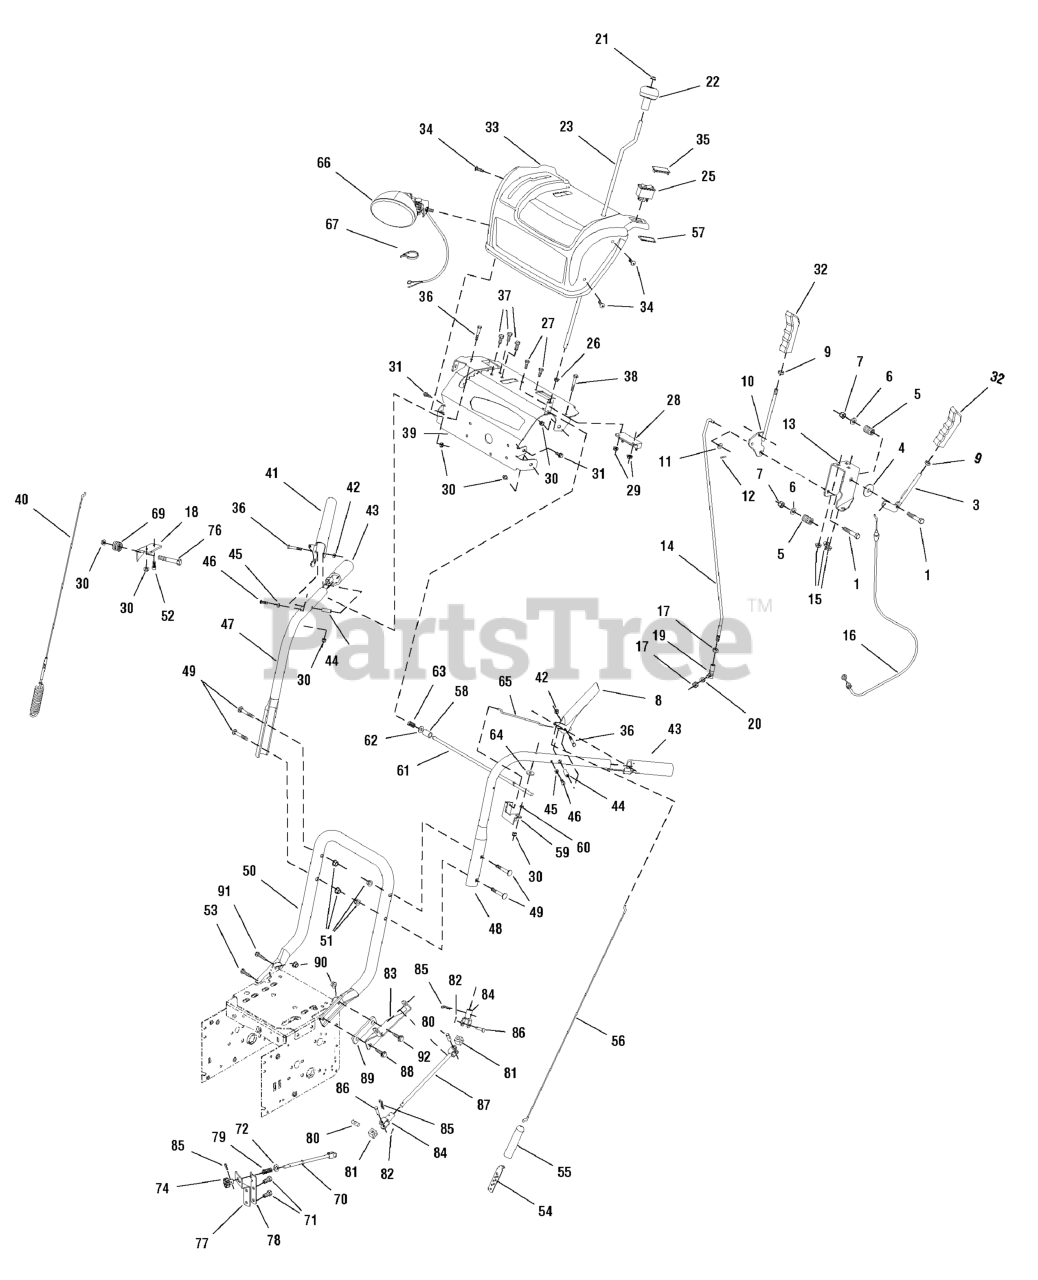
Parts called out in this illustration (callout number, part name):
1	CAPSCREW, Hex Head 3/8-16 x 2 G5
3	ROD, Chute
4	WASHER, 3/8
6	WASHER, 3/8
7	NUT, Hex Lock ESNA Light, 3/8-16
8	GRIP, Clutch L.H.
9	NUT, Hex Jam, 3/8-16
10	ROD & BRACKET ASSEMBLY, Speed
11	WASHER, 1/4
12	COTTER PIN
13	BRACKET, Control
15	NUT, Hex Flange Whiz Lock, 5/16-18
16	CABLE, Deflector Control
17	NUT, Hex 5/16-24
18	BRACKET, Spout Cable
19	BALLJOINT, Steel
20	LOCKWASHER, Spring 5/16
21	NUT, Push Pal Stud Capped 3/8
22	KNOB, Spinner
23	ROD, Chute Control
24	HARNESS, Wiring Hand Warmers
25	SWITCH, Rocker Hand Warmer
27	CARRIAGE BOLT, 1/4-20 x 3/4 G5
28	RESISTOR BLOCK
29	NUT, Hex KEPS, 1/4-20 Conical Washer
30	NUT, Hex Lock ESNA Light 1/4-20
31	SCREW, Hex Washer Head Taptite, 1/4-20 x 5/8
32	GRIP, Lever
33	COVER, Panel
34	SCREW, Truss Head Torx Drive 1/4-20 x 3/4
35	PLUG, Hole
36	CAPSCREW, Hex Head, 1/4-20 x 1-1/2 G5
37	CARRIAGE BOLT, 5/16-18 x 3/4 G5
38	CAPSCREW, Hex Head, 1/4-20 x 1-3/4 G5
39	SUPPORT, Dash Panel Cover
40	CABLE & SPRING ASSEMBLY, Auger Drive R.H.
41	GRIP, Clutch R.H.
42	NUT, Hex Centerlock 1/4-20
43	HAND GRIP, Heated
43	GRIP
44	SPACER, Handle
46	SCREW, Pan Head Torx, 1/4-20 x 3/4 Thread Cut
47	HANDLE, Upper R.H.
48	HANDLE, Upper L.H.
49	CARRIAGE BOLT, 5/16-18 x 2-1/4 G5
50	HANDLE, Lower
51	NUT, Hex Flange ESNA, 5/16-18
52	SCREW, Pan Head Torx
53	SCREW, Hex Washer Head Taptite, 5/16-18 x 3/4
54	BRACKET, Cable
55	BOOT, Control Spring
56	CABLE, Front Drive
57	SHIM, Hole Plug
59	BRACKET, Free Hand
60	SPACER, Powerdered Metal
61	ROD & SPRING ASSEMBLY, with Pin
62	WASHER, 1/2
63	SPRING, Compression
64	WASHER, 1/4
65	ROD, Hold Down
66	HEADLIGHT ASSEMBLY, Oval Clear
67	TIE, Self Locking
69	SPOOL CABLE, Auger Control
70	ROD & YOKE ASSEMBLY, Chute
71	CAPSCREW, Hex Head 3/8-16 x 3/4 G5
72	WASHER, 5/16
74	GEAR, 9 Tooth
76	CARRIAGE BOLT, 1/4-20 x 1-1/4 G5
77	BRACKET, Chute Gear
78	BRACKET, Spring
79	SPRING, Compression
80	PIN, Universal Joint
81	BLOCK, Universal Pivot
82	PIN, Cotter
83	SUPPORT, Chute Rod
84	YOKE & TUBE ASSEMBLY, Chute
85	PIN, Hair Chute Gear
86	PIN, Clevis
87	ROD & YOKE ASSEMBLY, Chute
88	SCREW, Hex Washer Head Taptite 5/16-18 x 1
89	SPACER, Block
90	NUT, Hex Flange Two-Way Lock, 5/16-18
91	CAPSCREW, Hex Head, 5/16-18 x 1 G5
92	CAPSCREW, Hex Head, 5/16-18 x 1-1/4 G5
